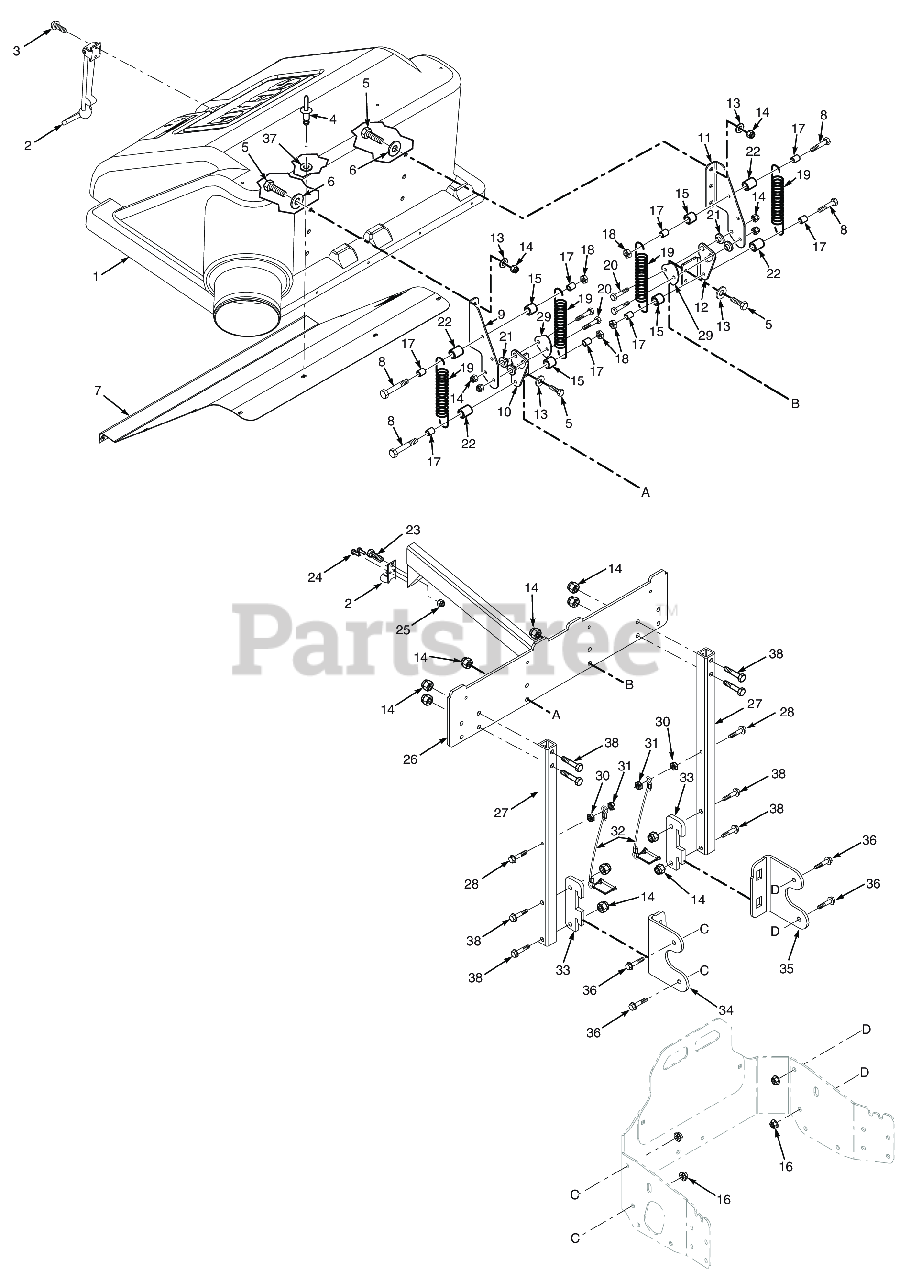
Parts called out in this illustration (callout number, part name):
1	Hood Assembly
2	Latch, Hopper
3	Screw, #10-32 x 3/4"
3	Flatwasher, 3/8-.196 x .496 x .048
3	HEX NUT, ELASTIC STOP LOCK # 10-32
4	Pop Rivet, 3/16 x .652"
5	Bolt, Hex Head 3/8-16 x 1-1/4", Kawasaki FX / FS
6	Flatwasher, 3/8-.406 x 1-1-1/2 x 7 Gauge
7	Screen, GC Hood
8	Capscrew, Hex Head 3/8-16 x 3-3/4"
9	Hinge, Upper RH
10	Hinge, Lower RH
11	Hinge, Upper LH
12	Hinge, Lower LH
13	Flatwasher, 3/8" Special (.391 x .938 x .105)
14	HEX NUT, ELASTIC STOP LOCK, 3/8-16
15	SPACER, J-PULL ROD
16	NUT, 3/8-16 SERRATED FLANGE HEX HEAD
17	Spacer, Deck Assist
18	Bolt, Hex Head 3/8-16 x 1" Ser. Flg.
19	Spring, Hood Hinge
20	Bolt, Hex Head, 3/8-16 x 1-1/2"
21	Bushing, Hopper Pivot
22	Spacer
23	BOLT, SERRATED FLANGE HEX HEAD 5/16-18 X 3/4"
24	Rivot, 3/16 x .402 POP
25	HEX NUT, ELASTIC STOP LOCK, 5/16-18
26	Frame Weldment, Bag Support
27	Tube, Grass Catcher Mount
28	Bolt, Hex Head 1/4-20 x 0.63"
29	Guard, GC Hinge
30	NUT, 1/4-20 SERRATED FLANGE HEX HEAD
31	Bolt, Hex Hd. 1/2-13 x 9-1/2"
32	Snap Pin Assembly w/Lanyard
33	Latch, GC-SFZ
34	Bracket, GC Mount RH
35	Bracket, GC Mount LH
36	Bolt, Hex Head, 3/8-16 x 1 Gr. 5
37	Flatwasher, 3/16 (.196 x .469 x .048)
38	Bolt, Hex Head 3/8-16 x 2-1/4" - 61"
